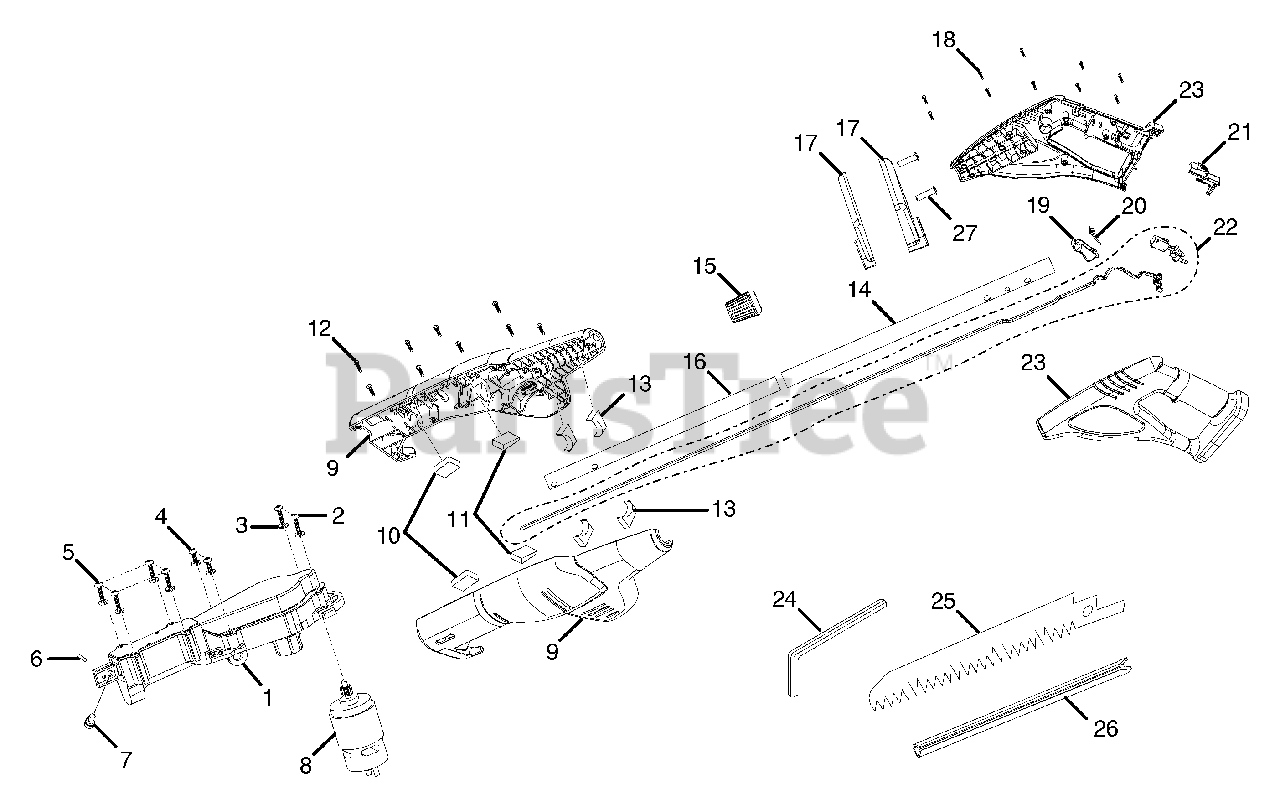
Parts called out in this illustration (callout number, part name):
1	GEAR BOX ASSEMBLY
2	SCREW (M4 X 28 mm)
3	SPRING WASHER
4	SCREW (M4 X 12 mm)
5	SCREW (M4 X 18 mm)
6	MOUNTING CLAMP
7	SCREW (M6 X 14 mm)
8	MOTOR ASSEMBLY
9	HOUSING ASSEMBLY
12	SCREW (M4 X 16 mm)
14	UPPER TUBE (23 mm)
15	COLLECTING CAP
16	LOWER TUBE (26 mm)
17	FRONT HANDLE ASSEMBLY
18	SCREW (M35 X 16 mm)
20	TRIGGER SPRING
21	SAFETY BUTTON
22	SWITCH ASSEMBLY
23	HAND HOUSING SUPPORT ASSEMBLY
26	SCABBARD
27	SCREW (M3 X 14 mm)
